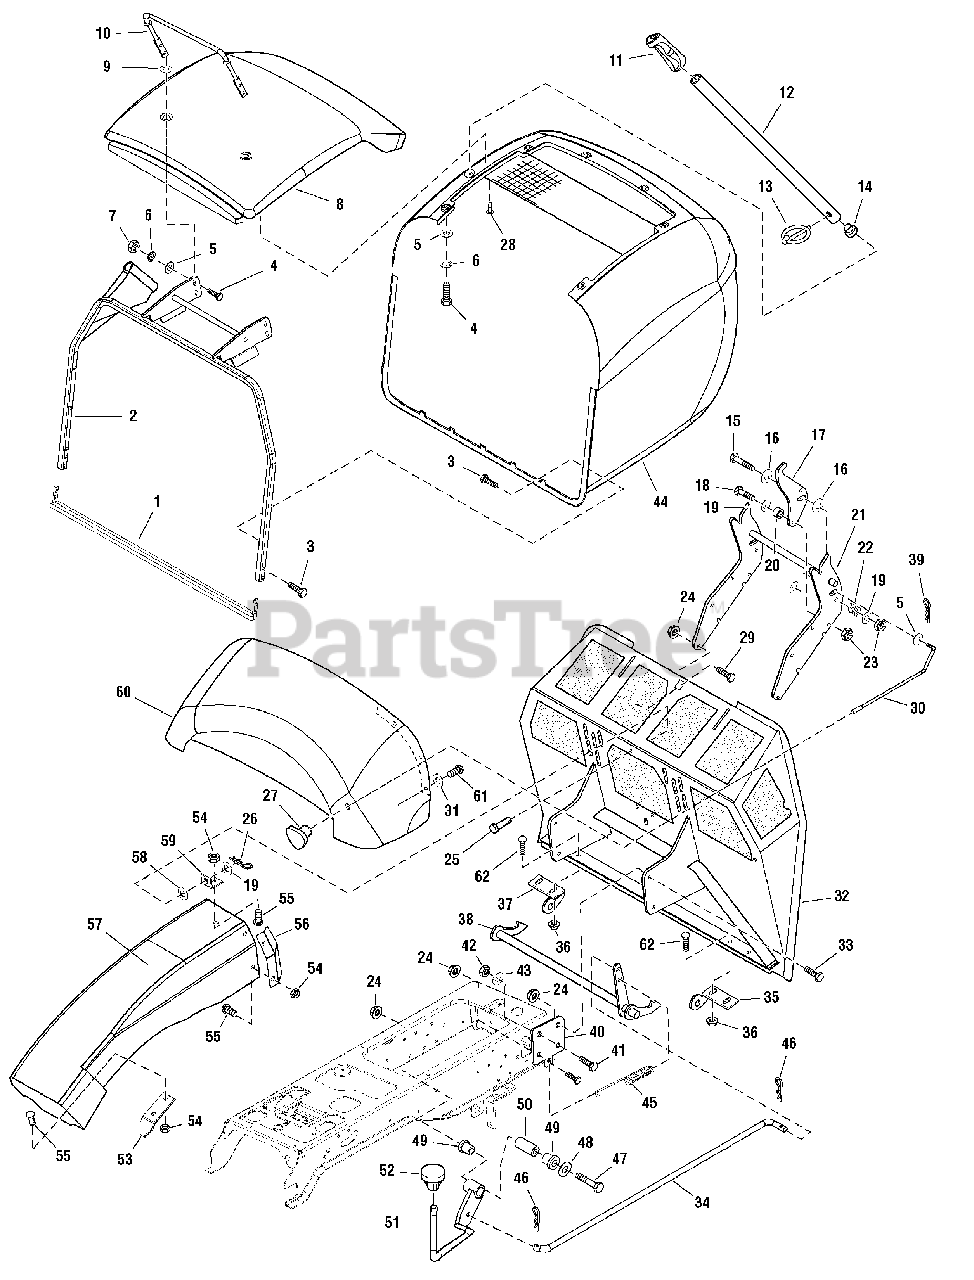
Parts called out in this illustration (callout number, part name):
1	ANGLE & BAR ASSEMBLY
2	FRAME ASSEMBLY
3	CAPSCREW, Hex Head Taptite, 1/4-20 x 1/2
4	CAPSCREW, Hex Head, 1//4-20 x 7/8
5	WASHER, 1/4
6	LOCKWASHER, 1/4
7	NUT, 1/4-20
8	LID, Hopper, Red
9	WASHER, Rubber
10	HANDLE, Hopper
11	GRIP
12	TUBE, Handle
13	PIN, Click
14	CAP PLUG, Rubber
15	CAPSCREW, Hex Head, 5/16-18 x 2
16	WASHER, 5/16
17	LATCH, Pivot
18	CAPSCREW, Hex Head, 5/16-18 x 1
19	WASHER
20	SPACER
21	PIVOT ASSEMBLY
22	SPRING, Compression
23	NUT, Hex Lock ESNA Light, 5/16-18
24	NUT, Hex Flange Lock, 3/8-16
25	PIN
26	PIN, Quick
27	KNOB
28	PANEL FASTNER
29	CAPSCREW, Hex Head, 3/8-16 x 3/4
30	ROD, Latch
31	WASHER, 1/4
32	BACKPLATE ASSEMBLY
33	CAPSCREW, Hex Head Whiz Lock, 3/8-16 x 1
34	ROD LATCH
35	BRACKET, Latch LH
36	NUT, Hex Flange Lock, 5/16-18
37	BRACKET, Latch, RH
38	SHAFT & ARMS ASSEMBLY
39	PIN, Cotter, 5/8 x 3.4
40	SUPPORT, Back Plate
41	CAPSCREW, Hex Head, 1/2-13 x 1
42	NUT, Hex, 1/2-13
43	LOCKWASHER, 1/2
44	HOPPER & SCREEN ASSEMBLY
45	SPRING, Extension
46	CLIP, Hair Pin
47	CAPSCREW, Hex Head, 3/8-16 x 2-1/2
48	WASHER
49	BUSHING
51	ROD & TUBE ASSEMBLY
52	KNOB, Hopper
53	RETAINER
54	NUT, Hex Lock ESNA, 1/4-20
55	SCREW, Torx Head, 1/4-20 x 5/8
56	DEFLECTOR, Grass
57	CHUTE, Discharge
58	NUT, Push
59	BRACKET, Chute
60	TRANSITION, Hopper
61	SCREW, Pan Head Torx Taptite, 1/4-20 x 3/4
62	CARRIAGE BOLT, 5/16-18 x 7/8 G5
